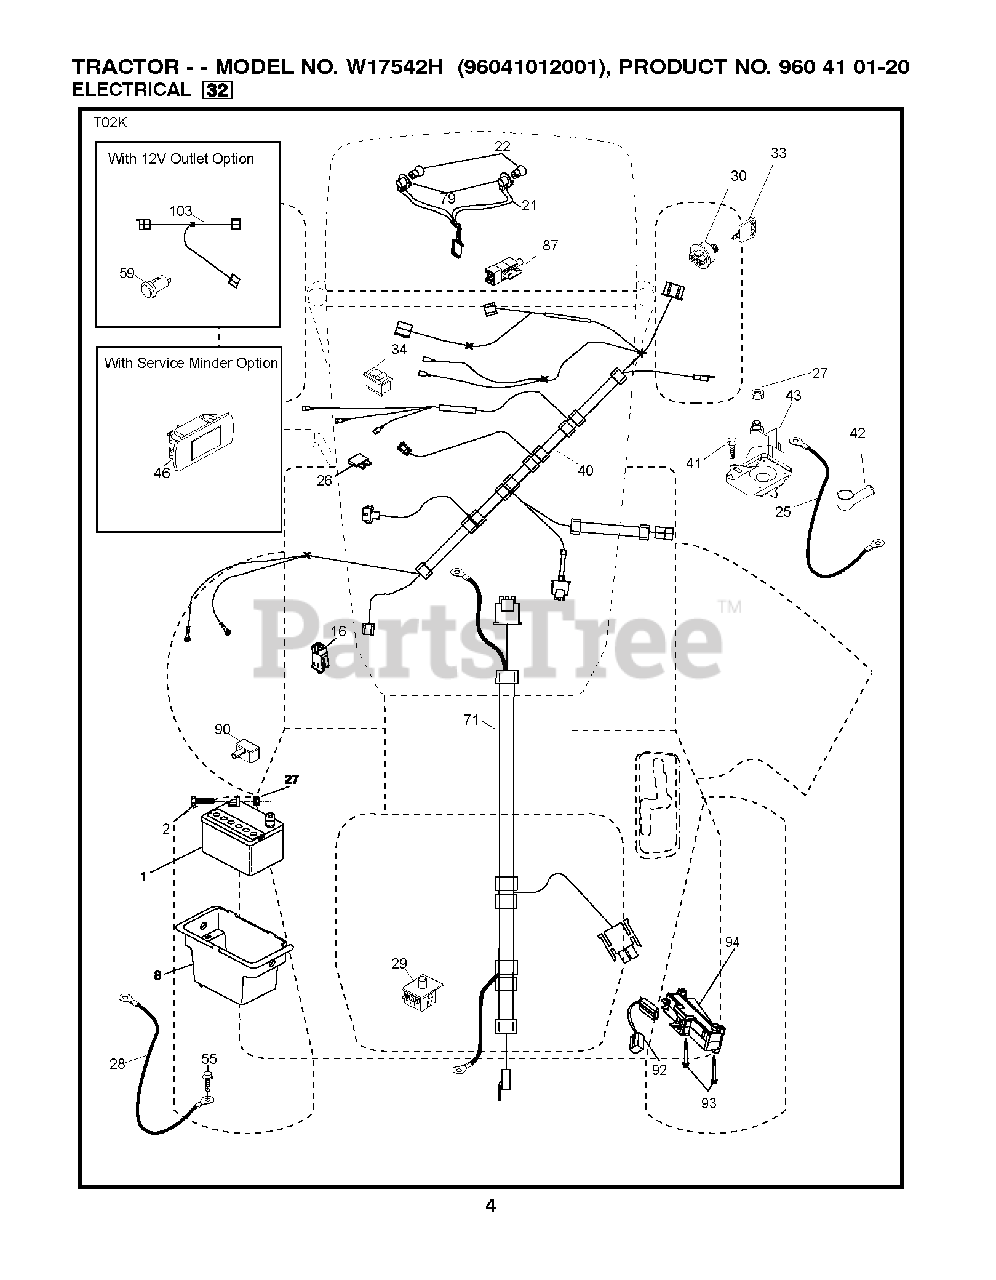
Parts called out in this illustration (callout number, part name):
1	REPL BY 532 12 38-99
2	BOLT.HEX.1/4.X.3/4.DICHROMATE
8	BOX.BATTERY.MNT.REAR.L
16	SWITCH INTERLOOK PUSH-IN
21	HARNESS ASSY LIGHT
22	LIGHTBULB
25	CABLE.STARTER.6GA.BL/RED.14.
26	FUSE 20AMP
27	NUT
28	CABLE.BLACK.18"REAR.BA
29	SWITCH.SEAT.DP W/RAMPS
30	SWITCH.IGN.DELTA.W.LGH.ROS
33	KEY.CHAIN.BLISTER.PACK.GEN.USA
34	SWITCH LT
40	HARNESS IGN. DASH
41	SCREW
42	TERMINAL COVER
43	SOLENOID.W/BRASS.PLUNGER
55	SCREW 5/16"
71	HARNESS.IGN.CHASS.TEX.REAR.BAT
79	BULB HOLDER ASM.
87	SWITCH.INTRLCK.CLUTCH.
90	COVER, TERMINAL BATTERY
92	HARNESS.PIGTAIL.CONSLE
93	SCREW.PLASTITE
94	MODULE.REVERSE.ROS
